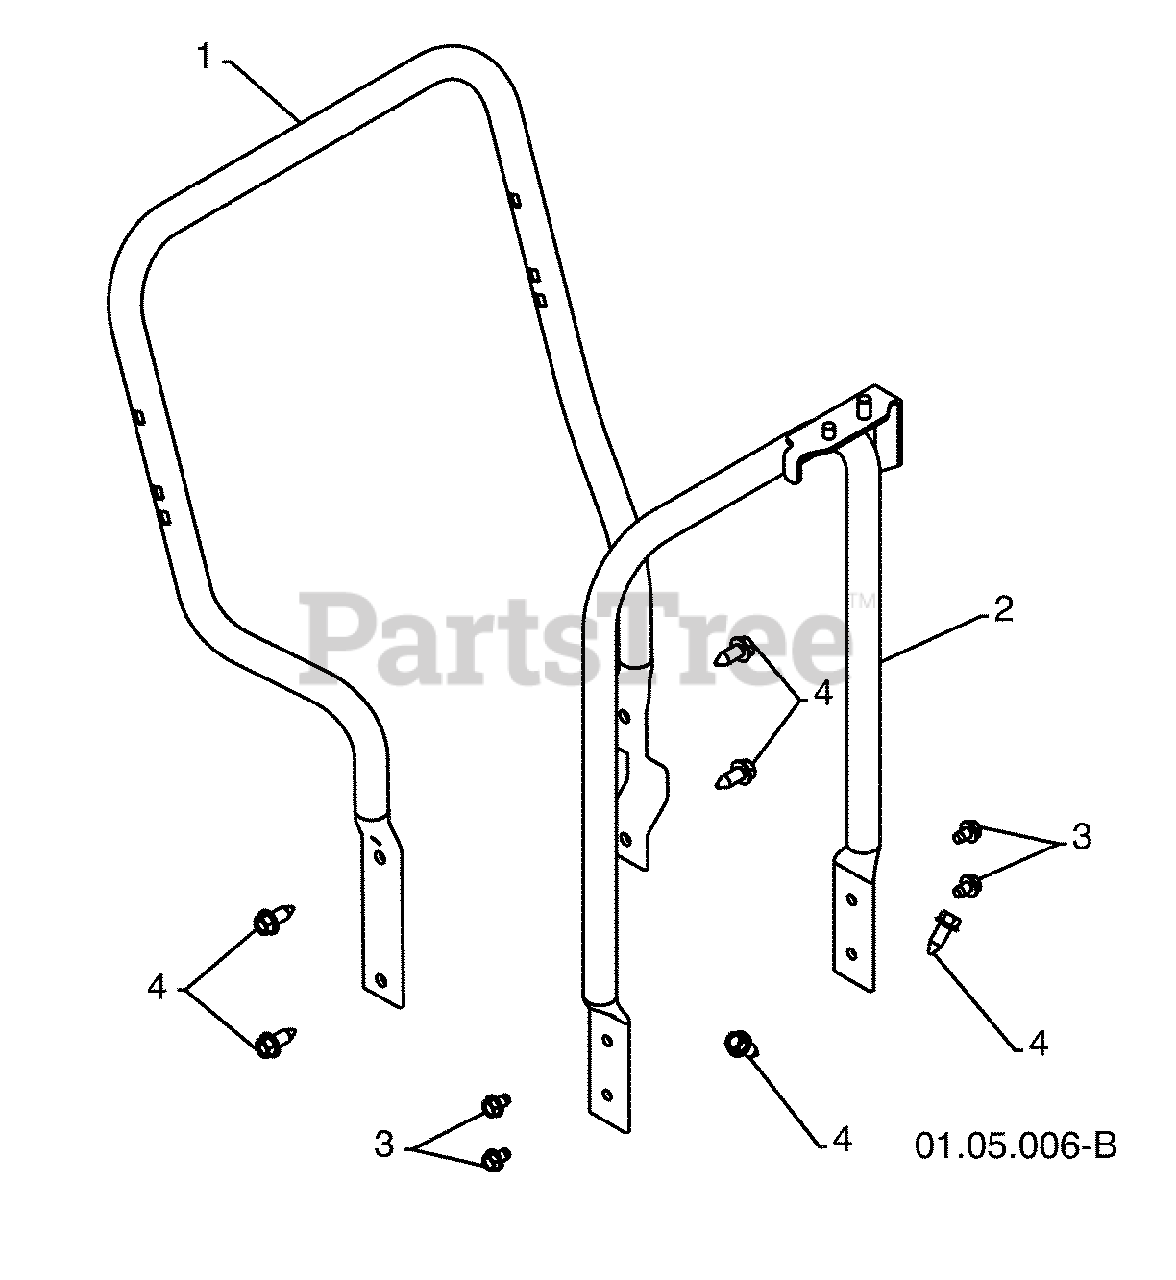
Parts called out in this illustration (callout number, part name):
1	LOWER TUBE GRAY
2	PIVOT SUPPORT
3	BOLT 5/16-18 X .750
4	SCREW 3/8-16 X 1.00
